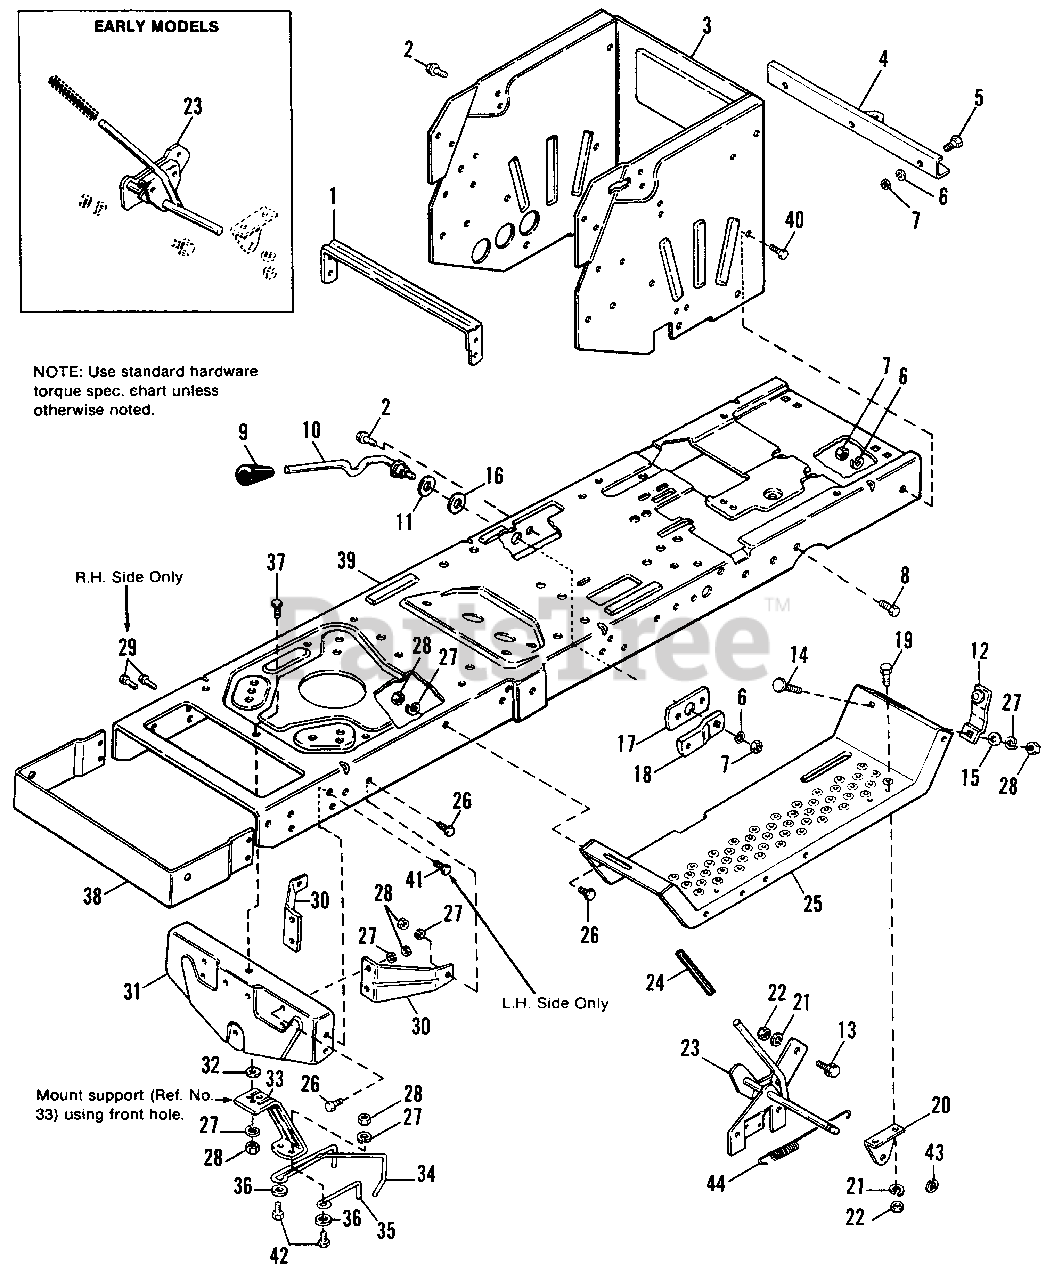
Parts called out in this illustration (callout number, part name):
2	SCREW, Taptite, 5/16-18 x 1/2
2	LOCKWASHER
3	SUPPORT, Axle Wrapper
4	BAR, Draw
5	CAPSCREW, Hex, 3/8-16 x 1, Gr. 5
6	WEAR PLATE
6	LOCKWASHER, 3/8
7	NUT, Hex, 3/8-16
9	GRIP, Handle
10	HANDLE, Lift
11	WASHER (If equipped)
12	LATCH ASSY.
13	CAPSCREW, Hex Wash. Hd., 1/4-20 x 5/8
14	CARRIAGE BOLT, 5/16-18 x 3/4
15	WASHER, Plain, 5/16
16	WASHER, Nylon
17	BAR, Support
18	ARM, Support
19	CAPSCREW, Hex, 1/4-20 x 5/8, Gr. 5
20	SUPPORT, Clutch
21	LOCKWASHER, 1/4
22	NUT, Hex, 1/4-20
23	LEVER ASSY., Clutch
23	LEVER ASSY., CLUTCH
24	GRIP, Handle
25	FOOTREST
26	CAPSCREW, Hex, 5/16-18 x 3/4
27	LOCKWASHER, 5/16
28	NUT, Hex, 5/16-18
29	SCREW, Taptite, 5/16-18 x 3/4
30	BRACE, Axle Support
31	SUPPORT, Axle
32	WASHER, Plain, 11/32-1 x 10 Ga.
36	WASHER, 1/4
37	CAPSCREW, Hex Hd., 5/16-18 x 1
39	FRAME
40	CAPSCREW, 3/8-16 x 1-1/2
41	SCREW, Taptite, 5/16-18 x 3/4
42	CAPSCREW, 5/16-18 x 7/8
43	RING, Retaining, 1/2
44	SPRING, Extension
